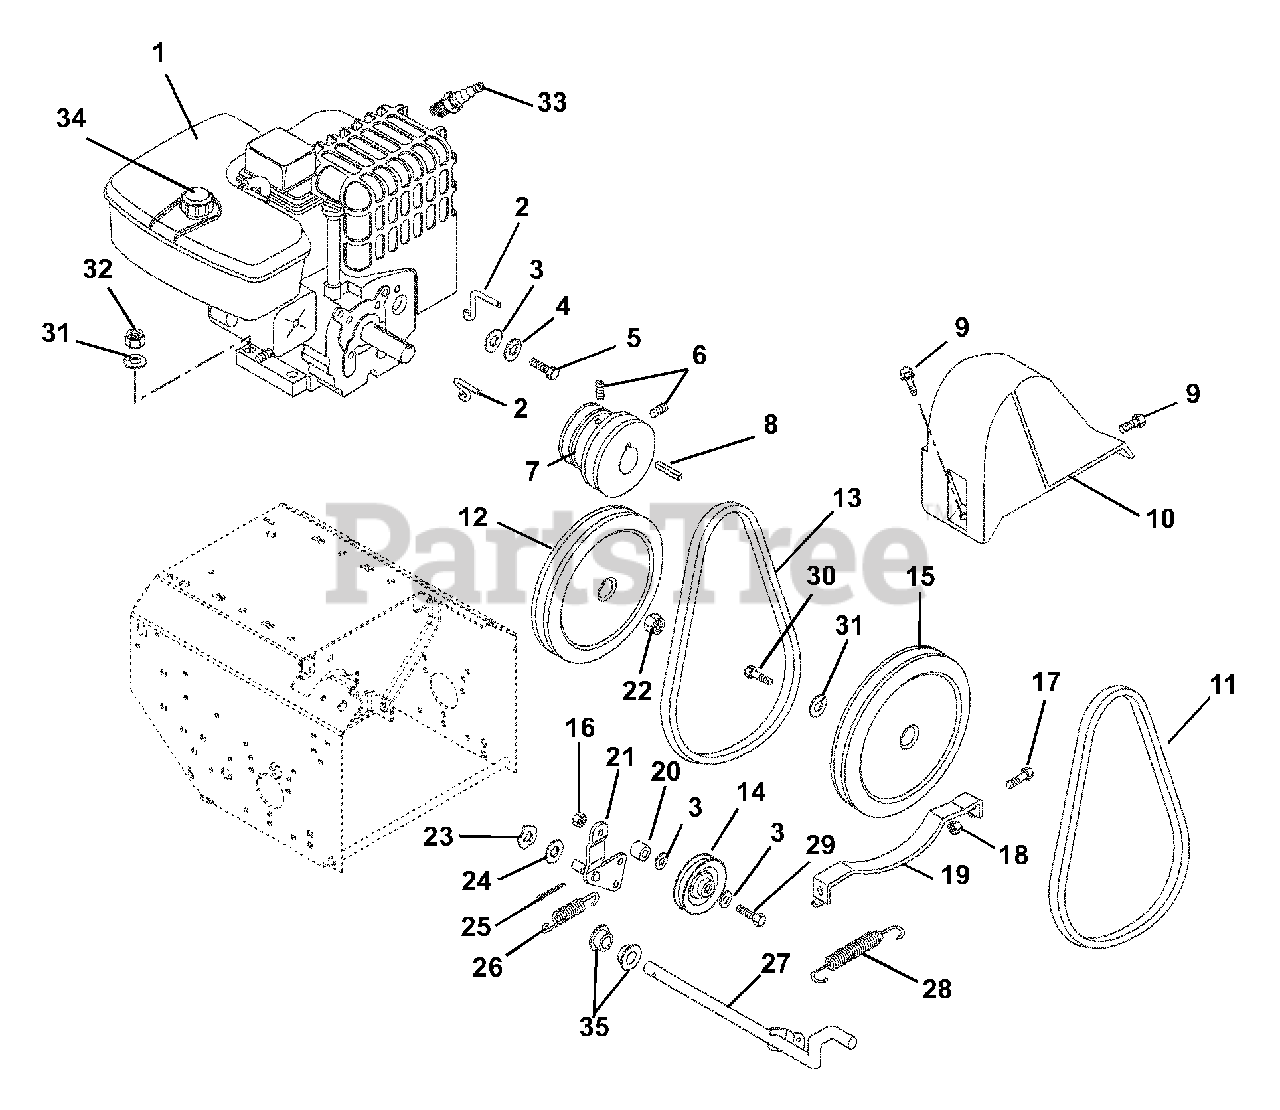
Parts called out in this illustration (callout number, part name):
1	Engine, 9HP Tecumseh OHV
2	Belt Finger
3	Washer, Flat Steel .38 x .88 x .083
4	Washer, Locking .31 x .078
5	Bolt, Hex .31-24 x .75 Grade 5
6	Screw, Set .31-18 x .38
7	Engine Sheave
8	Key, Straight .25 x 1.75 x .25
9	Screw, Tap .25-20 x .50
10	Belt Cover
12	Pulley-V 8.40 x 1.00 with Key
13	V-Belt,Traction Drive
14	Idler
15	Pulley .87 x 8.5
16	Nut, Locking Center .31-18
17	Bolt, Hex .25-20 x .50 Grade 5
18	Nut, Locking Center .25-20
19	Belt Retainer
21	Idler Arm
22	Nut, Locking Nylon .63-18
23	Wave Washer
24	Washer, Flat Steel .38 x .81 x .023
25	Pin, Cotter .09 x 1.00
26	Spring, Tension .80 x .73 x 3.06
27	Shaft, Activating
28	Spring, Tension .05 x .44 x 3.37
29	Bolt, Hex .31-18 x 1.00 Grade 5
30	Bolt, Hex .3-24 x .75
31	Washer, Locking .31 x .097 Heavy
32	Nut, Hex .31-18
33	Plug, Spark
34	Fuel Cap
35	Bushing, Flange .50 x.63 x.50 x.75
